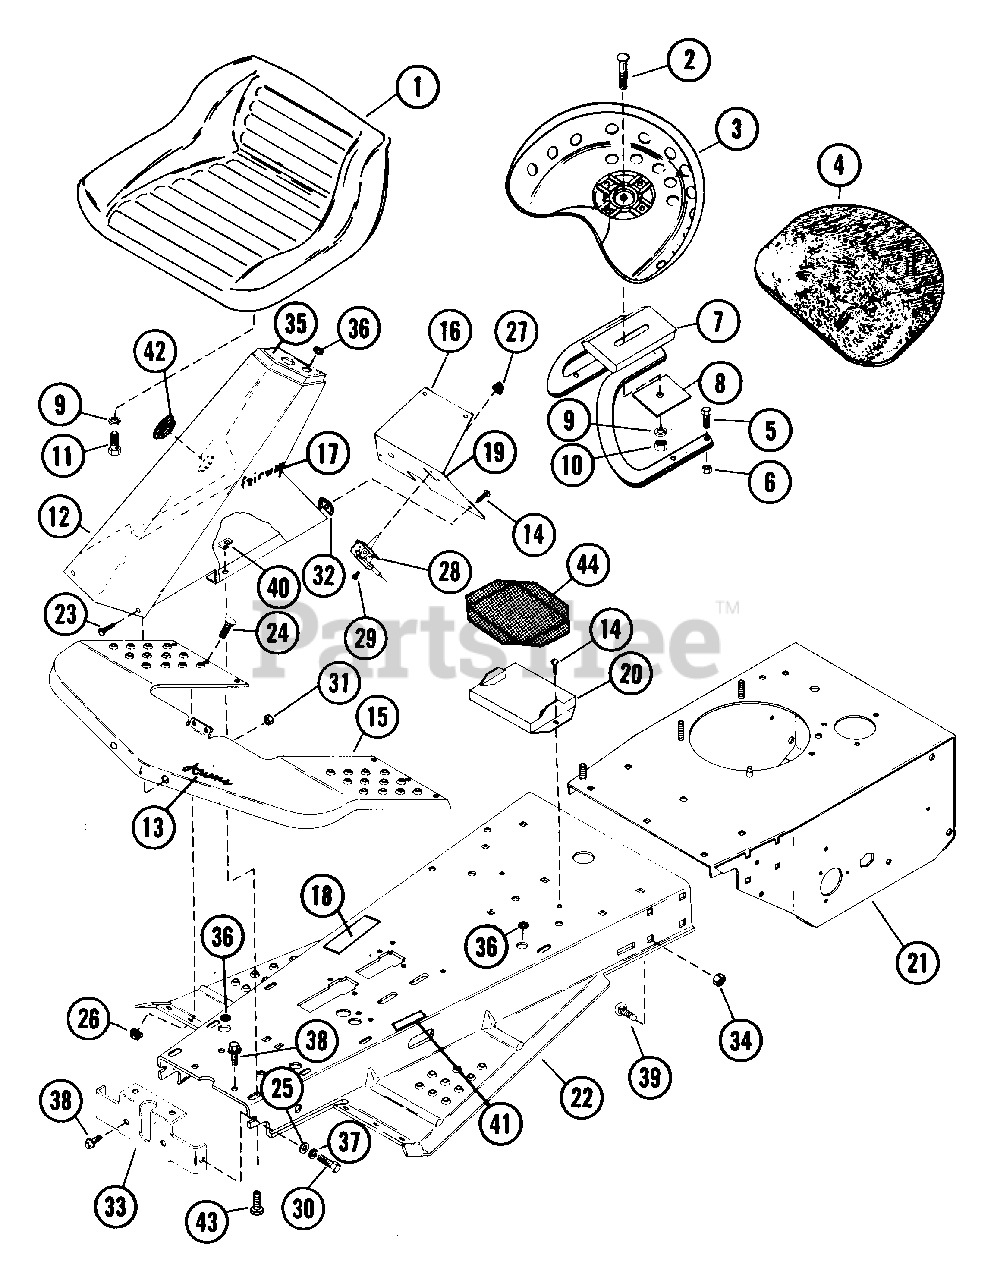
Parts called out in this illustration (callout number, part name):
1	TUBE LH SUPPORT
1	SEAT
2	TUBE R.H. SUPPORT
2	BLT-RDHDSQNK .50-13X1.25 PL
3	FRAME-TUBE
3	SEAT
4	SEAT COVER
5	BLT-HEX .31-18X1.50 PL GR2
6	SUPPORT TUBE
6	NUT-LK .312-18 GR A PL
7	GRASS CATCHER COVER ASSEMBLY
7	SEAT BRACKET
8	PLATE REINFORCEMENT
8	SEAT SUPPORT WASHER
9	WSHR-LK .500X.151 HVY PL
10	NUT .50-13 PL
11	BLT-HEX .50-13X1.25 PL GR2
12	TUBE BLANK
12	STEERING COLUMN
13	GRASS CATCHER CONE ASSEMBLY
13	ARIENS NAME PLATE
14	SCR-TAP 10-12X.50 CRPH PL A
15	FRONT FENDER
16	STRAP CONE
16	DASH PANEL ASSEMBLY
17	FAIRWAY NAME PLATE
18	CAUTION DECAL
19	DASH DECAL
20	STUD-WEIGHT
20	BATTERY RETAINER
21	REAR FRAME
22	BLT-HEX .25-20X2.50 PL GR2
22	FRONT FRAME ASSEMBLY
23	BATTERY STRAP
23	SCR-MCH 10-24X.38 SLTOR PAN PL
24	HOOK
24	SCR-SLTR-SERNK .25-20X.62 PL
25	NUT-LK-CTR .250-20 PL
25	WSHR-FL-STL .38X.875X.083 PL
26	SCR-MCH .31-18X1.50 CROVCNTRS
26	NUT-LK-FLG .250-20 PL
27	NUT-LK-NYL.312-18 PL
28	PIN-HAIR INT .08X.38X1.42 YWZC
28	THROTTLE CONTROL
29	BLT-SERHFWH .25-20X.50 PL
29	RVT-POP.125 X .294 DOME
30	BLT-SCRHFWH .25-20X.62 PL
30	BLT-HEX .31-18X.75 PL GR2
31	NUT-LK DUAL FACE 10-24 PL
32	CLEVIS PIN
32	NUT-SPEED U TYPE 10A
33	PIN-COTR .06X.50
33	FRONT FRAME SUPPORT
34	NUT-FLG. .312-18 PL
35	PARKING BRAKE DECAL
36	GROMMET, .31 ID
37	MOWER BLADE
37	WSHR-LK .312X.097 PL HVY
38	NUT-LK-FLG .250-20 PL
38	BLT-LK .31-18X.75 GR 5
39	CLIP CONE
39	BLT-RDHDSQNK .31-18X.75 GR5 PL
40	NUT-WING W/INSERT .312 - 18
40	NUT-SPEED U-TY .312-18
41	MOWER IN-OUT LABEL
43	BLT-HEX .31-18X1.50 PL GR2
43	BLT-HEX .31-18X.50 PL GR2
44	BAR SUPPORT
44	RUBBER PAD
45	BRACKET ADAPTER
46	BRACKET MOUNTING
48	WARNING DECAL
49	WSHR-FL-STL .438X1.0X.083 PL
50	WSHR-FL-STL .511X1.441X.125 PL
51	WARNING DECAL
52	CAUTION DECAL
53	NUT-LK-CTR .50-13
54	NUT-LK-TWIN .312-18 PL
55	PIN-HAIR INT .09X.62X2.25
56	WIRE HOOK
57	SCR-THUMB .31-18X.50 PL
58	NUT-SPEED U-TYPE .312-18
